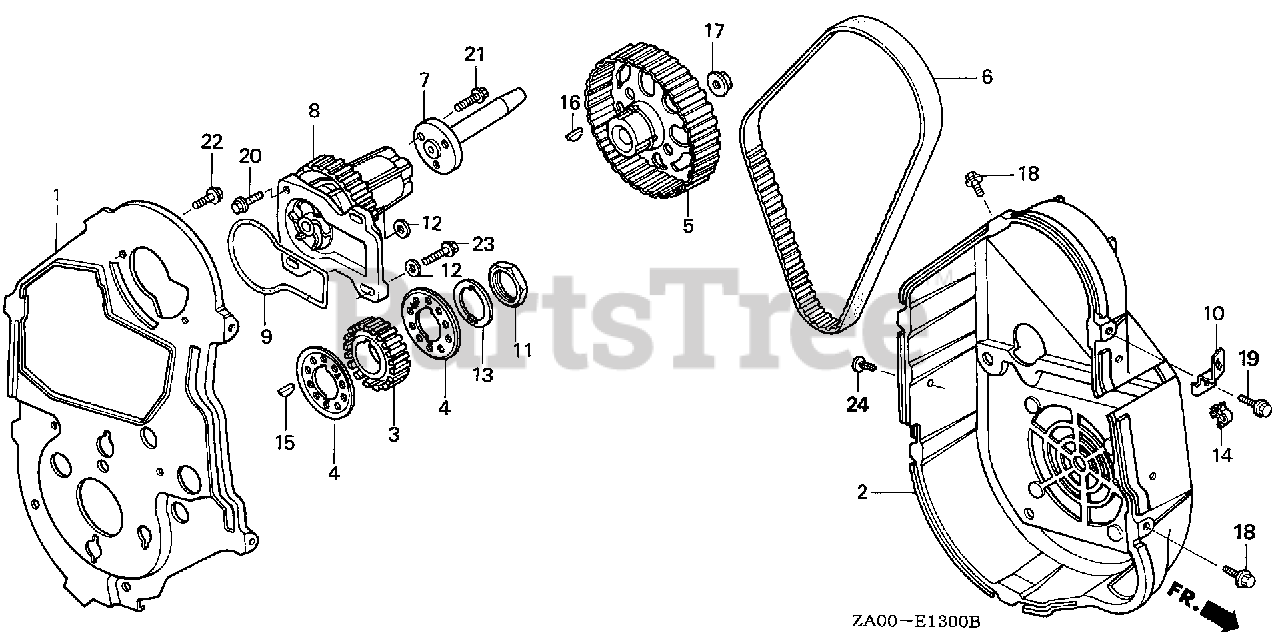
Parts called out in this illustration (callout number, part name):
1	COVER B, TIMING BELT
2	COVER A, TIMING BELT
3	PULLEY, TIMING
4	FLANGE, TIMING PULLEY
5	PULLEY, CAMSHAFT
6	BELT, TIMING
7	SHAFT, COOLING FAN
8	WATER PUMP
9	O-RING, WATER PUMP
10	BRACKET, IGNITION WIRE CLIP
11	NUT, LOCK (30MM)
12	WASHER, PLAIN (6.5X15)
13	WASHER, LOCK (30MM)
14	CLIP, ENGINE STOP SWITCH CORD
15	KEY, SPECIAL WOODRUFF (25X18)
16	KEY, CAM PULLEY
17	NUT, FLANGE (10MM)
18	BOLT, FLANGE (6X10)
19	BOLT, FLANGE (6X12) Use from Engine SN 2086984.
20	BOLT, FLANGE (6X22)
21	BOLT, FLANGE (6X20)
22	BOLT, FLANGE (6X12)
23	BOLT, FLANGE (6X22)
